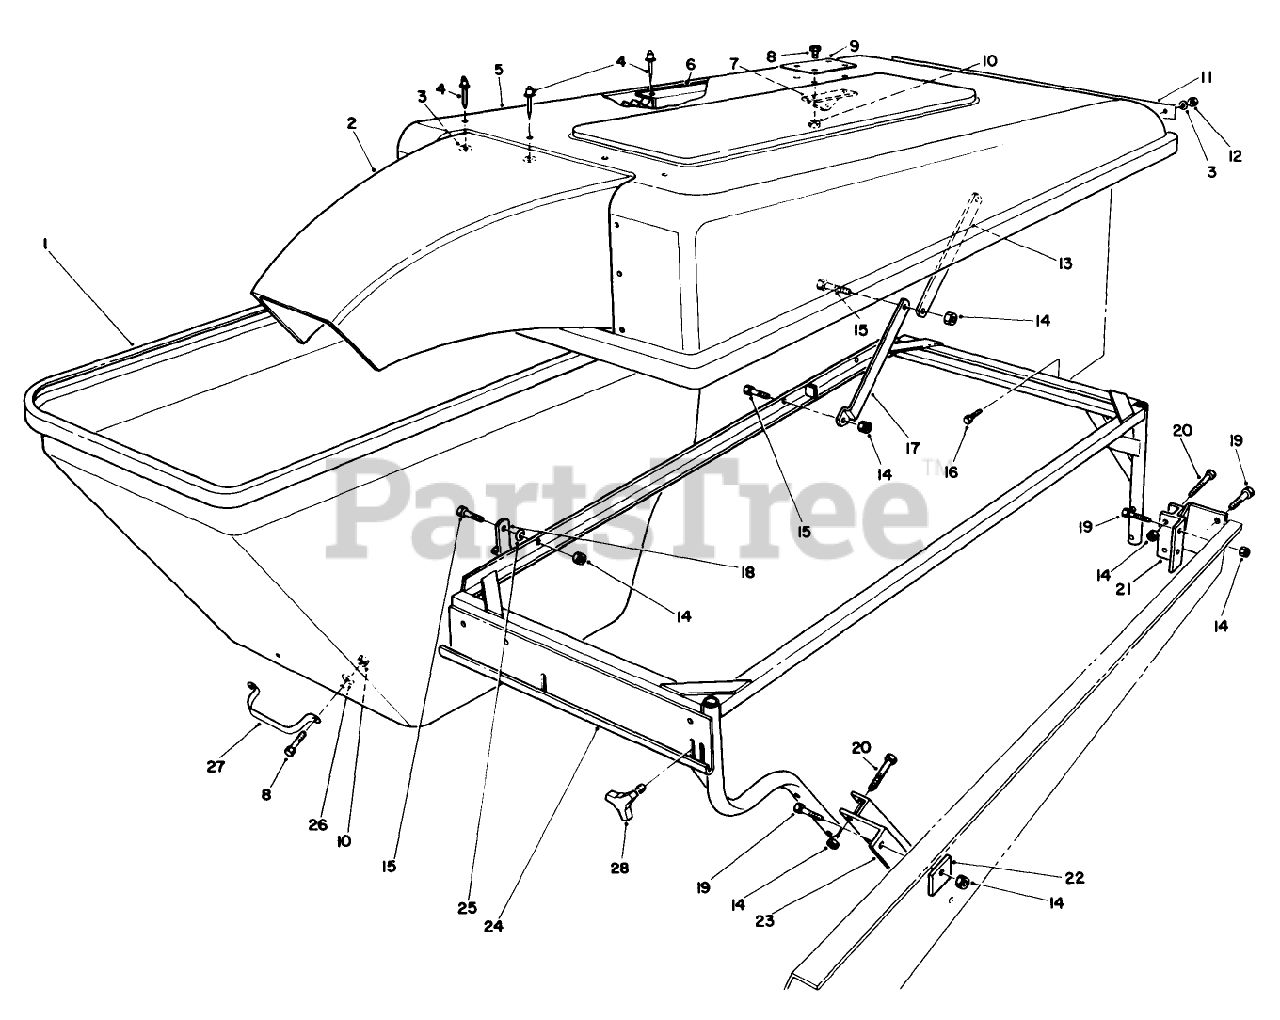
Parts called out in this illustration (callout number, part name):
3	WASHER-FLAT
4	RIVET-POP
8	SCREW-HH
10	NUT-LOCK, NI
11	HINGE PLATE
12	NUT-LOCK, NI
14	NUT-LOCK, NI
15	SCREW-HH
19	SCREW-HH
20	SCREW-HH
24	HOPPER FRAME WA
25	WASHER-SPRING
26	WASHER-FLAT
27	Handle
